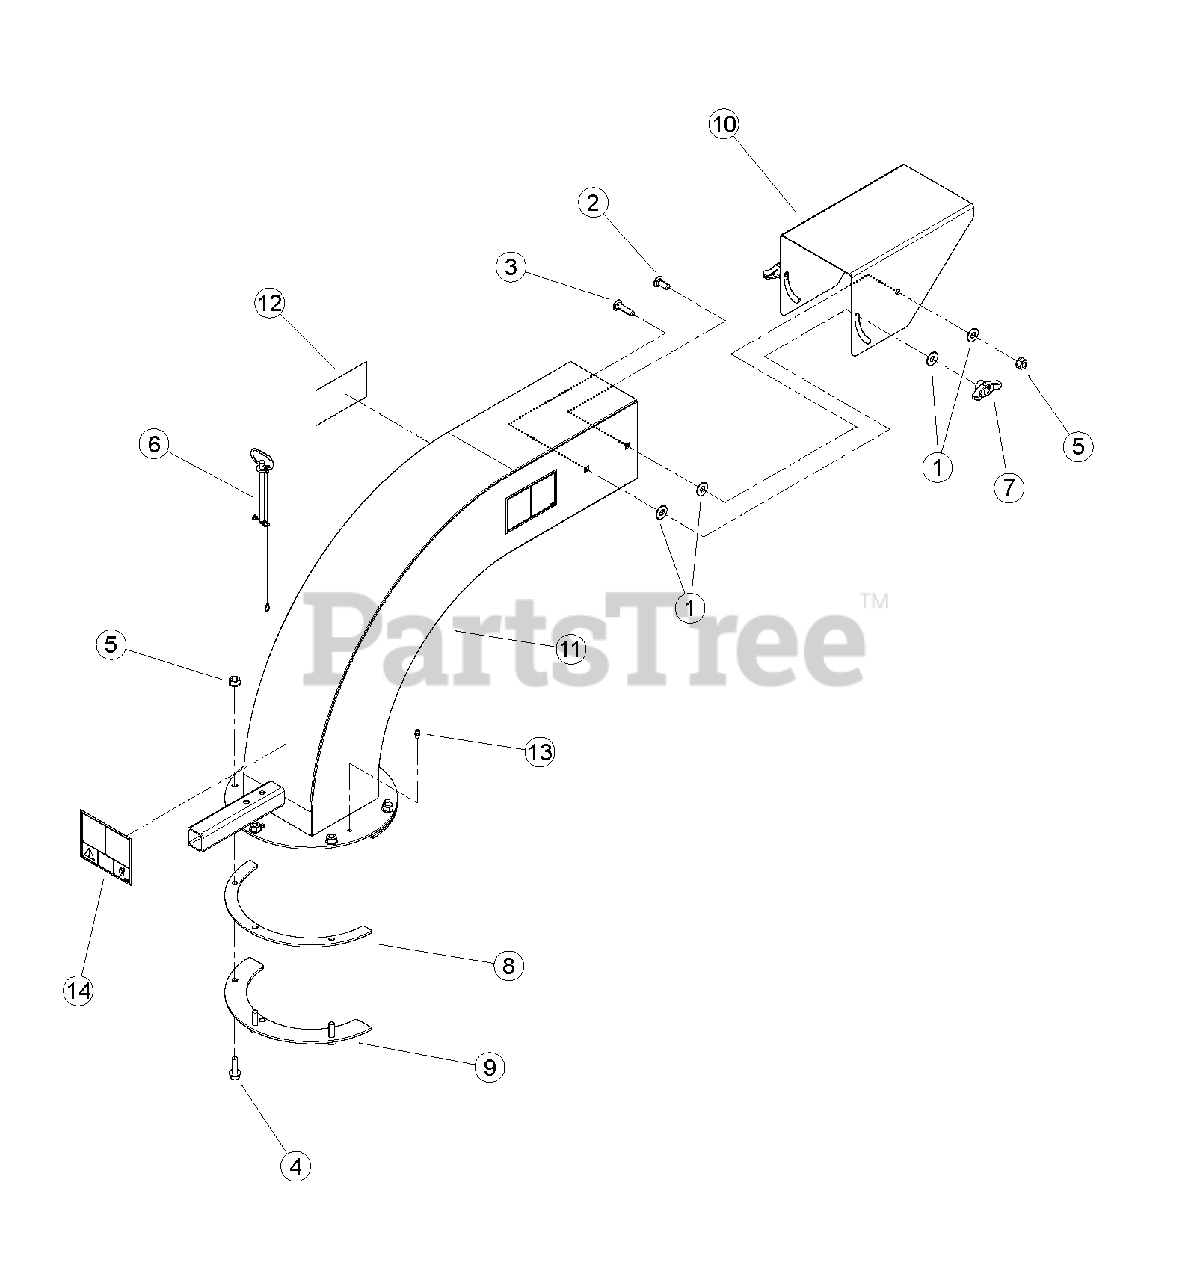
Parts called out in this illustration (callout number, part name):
1	WASHER, 3/8" FLAT ZP
2	BOLT, 3/8 X 1" GR5 CRG NC ZP
3	BOLT, 3/8 X 1-1/2"GR5 CRG NC ZP
4	BOLT, 3/8 X 1-1/4 FLANGE NC
5	NUT, 3/8-16 NYLOCK FLANGE
6	PIN, 3/8 X 4.25" DISCHARGE
7	KNOB, 3/8-16 UNC FEMALE TEE
8	RING, DISCHARGE SPACER
9	RING, DISCHARGE CLAMP
10	CAP, ORCHARD DISCHARGE
11	ASSEMBLY, ORCHARD DISCHARGE W/ DECALS
12	DECAL, DISCHARGE ISO
13	FITTING, 1/4 SELF-TAP GREASE
14	DECAL, DISCHARGE DEBRIS & LOCK
